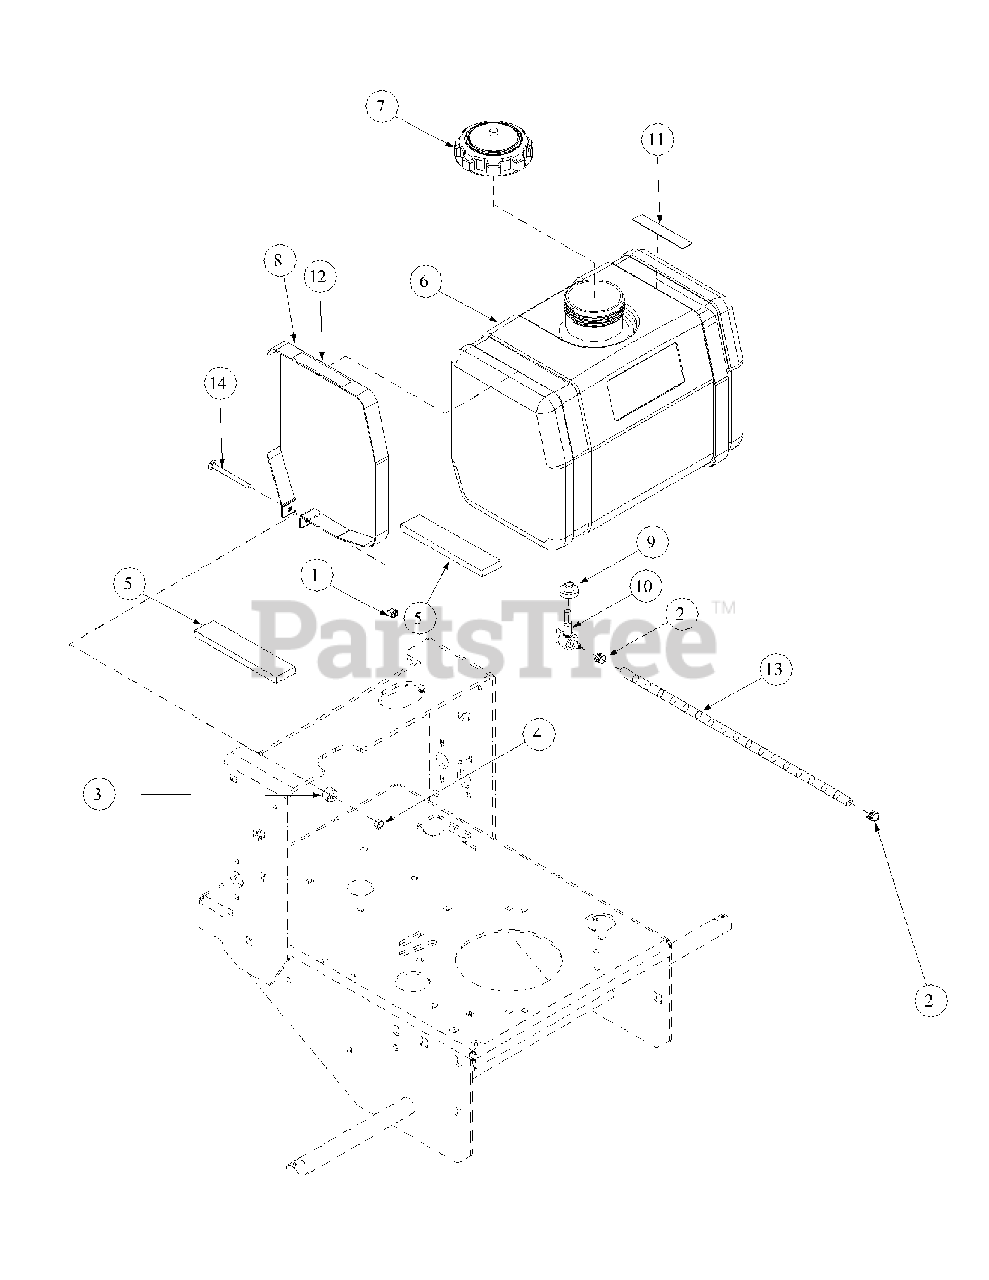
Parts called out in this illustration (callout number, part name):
1	Lock Nut, Nylon Insert, 1/4-20
2	Uni-Clamp
4	Nut, 1/4-20
5	Rubber Stop Pad
6	Fuel Tank
7	Fuel Cap, 3.5
8	Fuel Tank Strap
9	Grommet Fuel Tank
10	Shut Off Fuel Tank
11	Label, Mower Warning Turn Off Engine
12	Label, Mower Instruction, Fuel Valve
13	Hose Fuel, 18" x .25 ID
14	Carriage Bolt, 1/4-20 x 3.00
